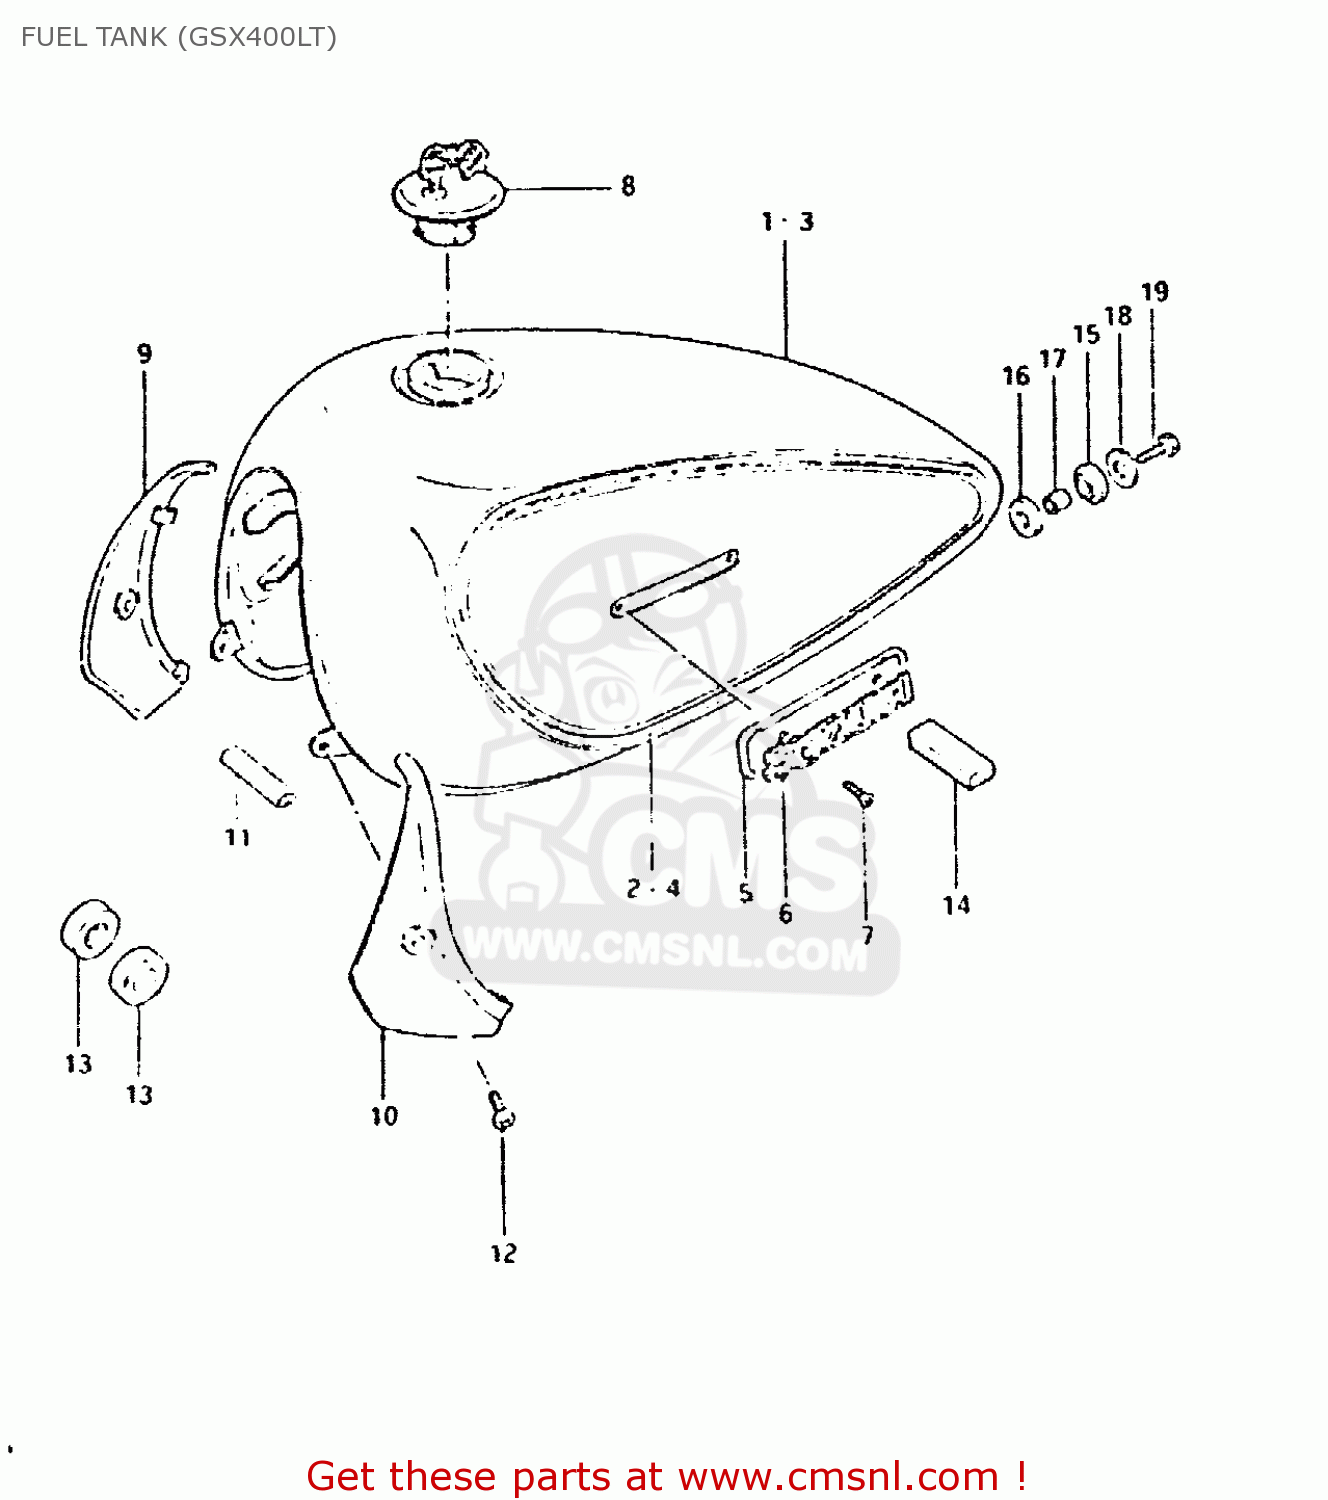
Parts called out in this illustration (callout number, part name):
1	TANK ASSEMBLY,FUEL
2	TAPE SET,FUEL TANK STRIPE
3	TANK ASSEMBLY,FUEL
4	TAPE SET,FUEL TANK
6	EMBLEM,FUEL TANK
7	SCREW 3X6
8	CAP SET,FUEL TANK
9	COVER,FUEL TANK,FRONT,RIGHT
10	COVER,FUEL TANK,FRONT,LEFT
11	TUBE, FRONT
12	SCREW 6X12
13	CUSHION
14	CUSHION
15	CUSHION
16	CUSHION
17	SPACER(8.5X12X19)
18	WASHER (8.5X29X1.6)
19	BOLT (8X30)
